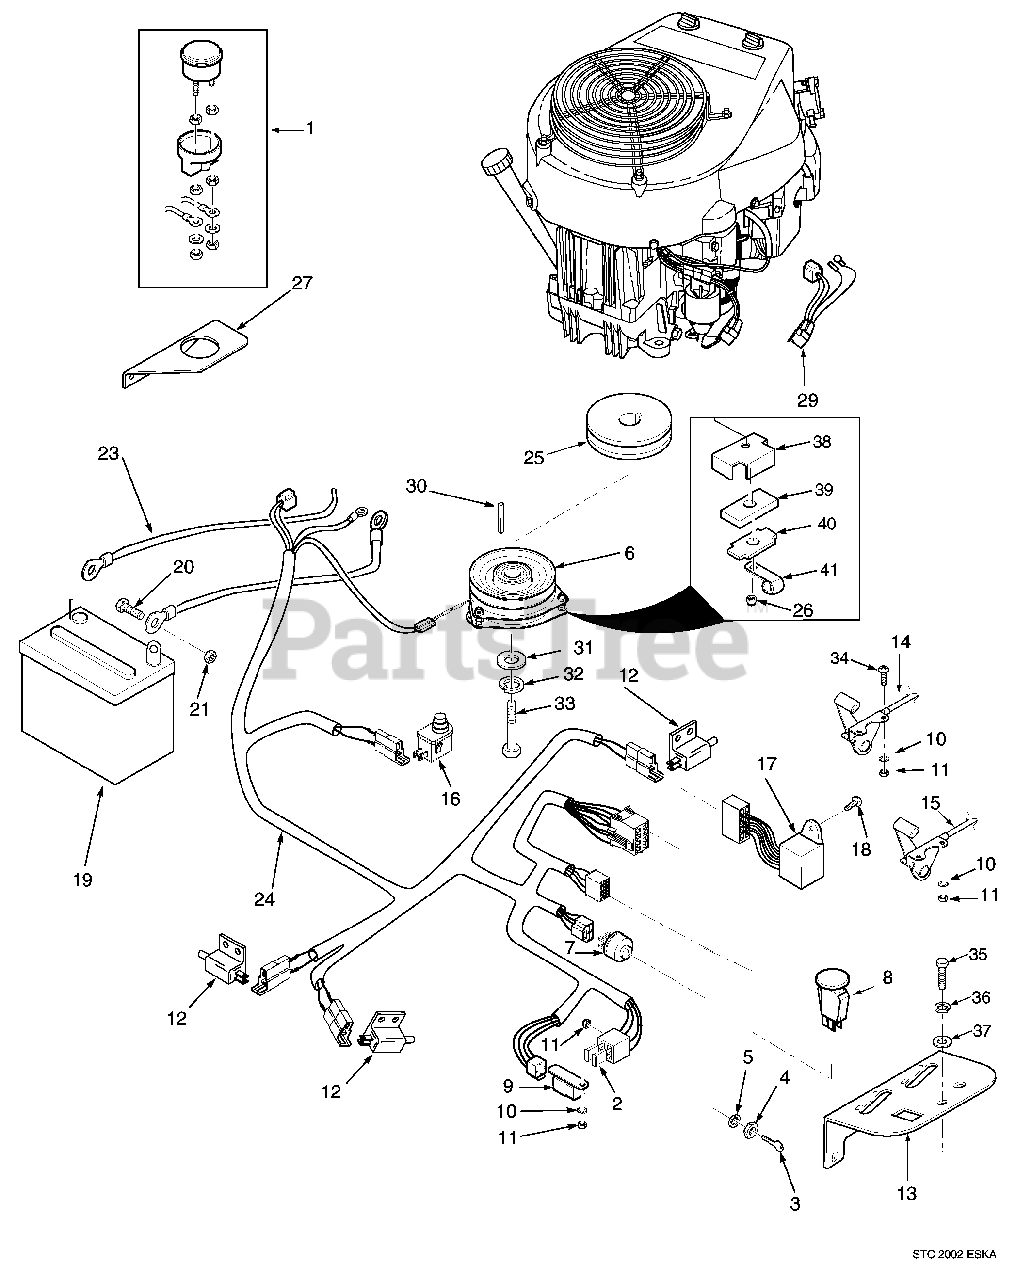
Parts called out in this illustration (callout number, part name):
1	Hourmeter
2	Fuse, 20 amp
3	Key, Ignition
4	Nut, Hex 5/8-32
5	Lockwasher, 5/8" Internal
6	Electric PTO Clutch GT3.5
7	Switch, Ignition
8	Switch, PTO
9	Relay
10	Lock Washer, #10 External Tooth
11	Nut, Hex #10-32
12	Switch, N/O
13	Panel, Instrument
14	Choke & Throttle Control - Kawasaki
15	Throttle Control - Kohler
16	Switch, Seat
17	Module, Interlock
18	Screw, #10-32 x .5" Phillips Head
19	Battery
20	Bolt, Hex Head 1/4-20 x .5"
21	Nut, Hex 1/4-20
22	Cable, Battery Black (negative)
23	Cable, Battery Red (positive)
24	Wiring Harness, Main
25	Pulley, 5.45 OD x 1.125 Bore
26	Nut, Elastic Stop 5/16-18 Key
27	Mounting Bracket, Hour Meter
28	Screw, #10-32 x 1.5" Phillips Head
29	Adaptor, Wiring Harness (Kawasaki only)
30	Key, 1/4 x 1/4 x 3-1/4"
31	Flatwasher, 7/16-.469 x 1-3/4" x 1/4"
32	Lockwasher, 7/16"
33	Bolt, Hex Head 7/16-20 x 2-1/2" UNF
34	Screw, #10-32 x 3/4"
35	Bolt, Hex Head 5/16-18 x 3/4"
36	Lockwasher, 5/16
37	Flatwasher, 5/16-.375 x .875 x .083
38	Backing Plate
39	Rubber Pad, Clutch Stop
40	Plate, Backing
